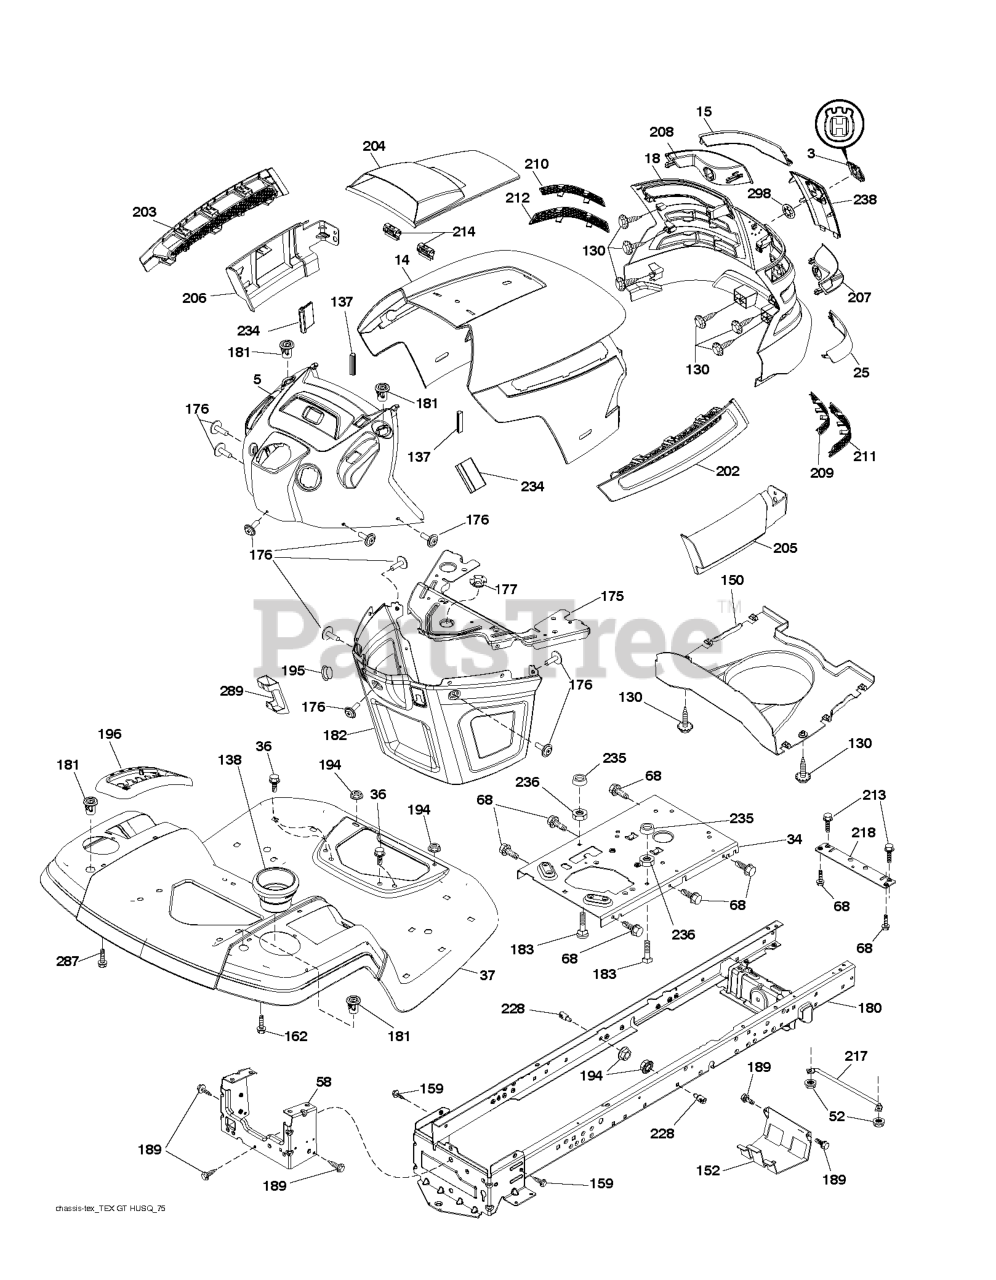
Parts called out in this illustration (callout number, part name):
3	LOGO.HUSQ.GT.LT.CROWN.H
14	HOOD
15	LENS.LH.TEX.GT.HUSQ.CL
18	GRILL.ASM.HUSQ.TG/CRD.W/TRIM
25	LENS.RH.TEX.GT.HUSQ.CL
34	PLATE.ENGINE.WELDED.CHASSIS
36	SCREW 5/16"
37	RP FENDER.TLT.FS.W/CPH.422
52	LOCKNUT
58	DRAWBAR UPPER 2PC SMALL FENDER
68	Screw 5/16-18 x 1/2 Hex, Self Tapping 5/16-18 x 1/2
130	SCREW.#10 X 0.750.BOS
137	BUMPER DASH
138	CUPHOLDER.TL.TEX.418
150	AIR.DUCT.TEXGT.HUSQ.31
152	SHIELD.BROWNING.W/TEX
159	SCREW, 3/8-16X3/4
162	SCREW.HI-LO.CONSOLE
175	PLATE.CROSSMEMBER.HUSQ
176	SCREW.#10-24X5/8.RN.QU
177	BUSHING, STEERING
180	CHASS.WLDMNT.TL.12GA/2P.48/54
181	BUSHING.MNT.FEND.CRGO.
182	DASH.LOWER.COMMON.12V.ADAPTOR
183	BOLT.5/16-18X1-1/4 FULL THD
189	SCREW
194	NUT LOCK HEX FLANGE 5/16-18
195	PLUG.HOLE.DASH.LOWER.12V.BLK
196	RP CONSOLE.ASM.DECKLFT.GR/RBT.
202	VENT.SIDE.HOOD.HUSQ.RH.GREY
203	VENT.SIDE.HOOD.HUSQ.LH.GRAY
204	HOOD VENT
205	SKIRT.HOOD.SIDE.HUSQ.RH.GREY
206	SKIRT.HOOD.SIDE.HUSQ.LH.GREY
207	BEZEL.RH.TEX.GT.HUSQ
208	BEZEL.LH.TEX.GT.HUSQ
209	INSERT.HEX.GRILL.HUSQ.GREY
210	INSERT.HEX.GRILL.HUSQ.
211	INSERT.HEX.GRILL.HUSQ.
212	INSERT.HEX.GRILL.HUSQ.
213	BOLT
214	CLIP.RETAINER.TINNER.
217	ROD.PIVOT.HOOD
218	X-PIECE.HOOD.STOP.NON/
228	STUD.FASTNER.W/ANTI-ROTATE
234	BUMPER.HOOD.TEX.HUSQVARNA
235	SPACER FENDER
236	NUT.CENTERLOCK.5/16-
238	TRIM.HUSQ.TG/CRD.SERVICE
287	SCREW 1/4X20
289	PLUG.N/CRUISE.COMMON.YT/GT.BLK
298	NUT PUSH M
